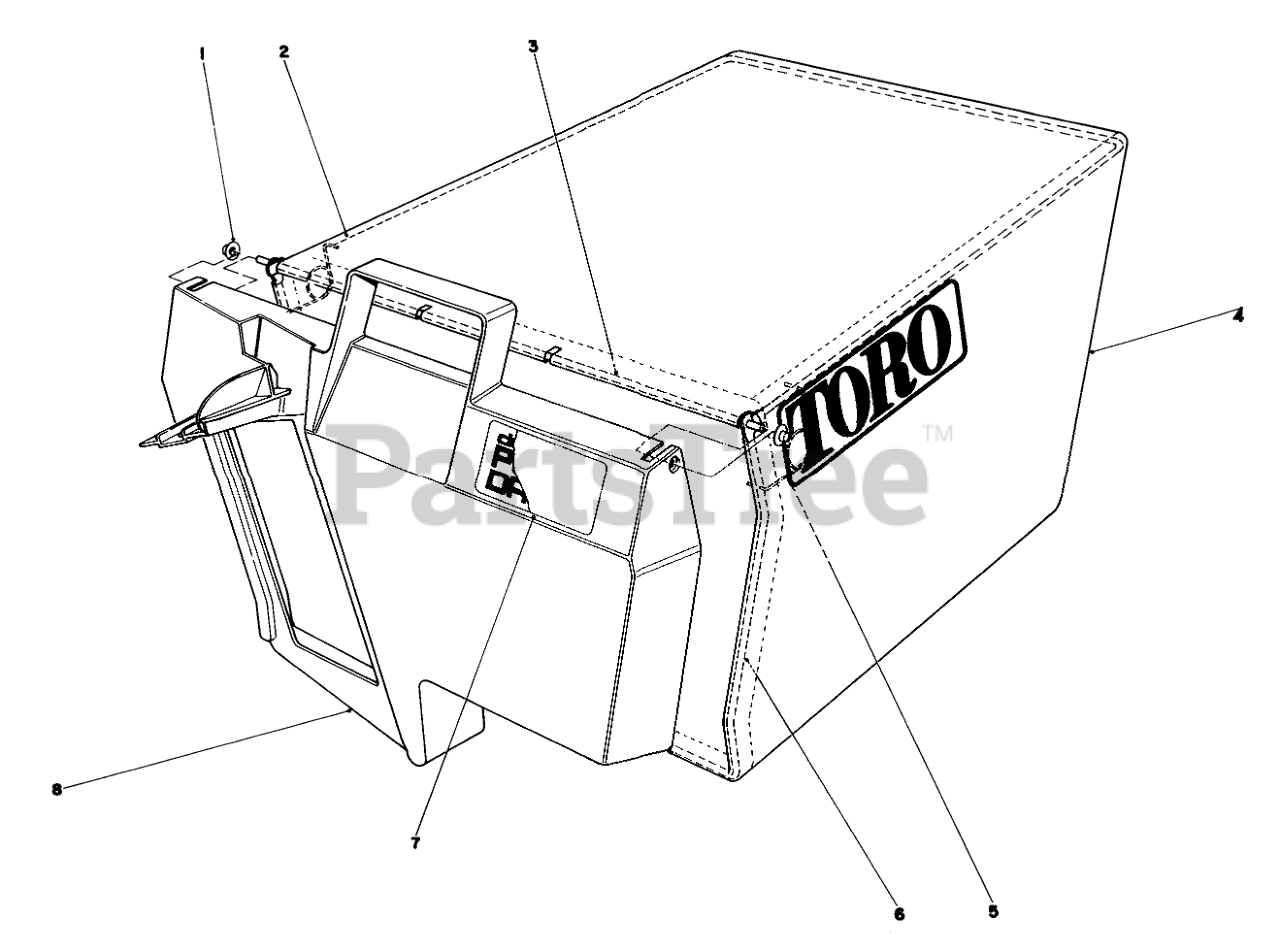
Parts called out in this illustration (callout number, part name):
1	NUT-PUSH
2	Bag Frame Upper
3	HingeBag Door
4	Bag
5	SPRING
6	BAG FRAME
7	Door Grass Bag
